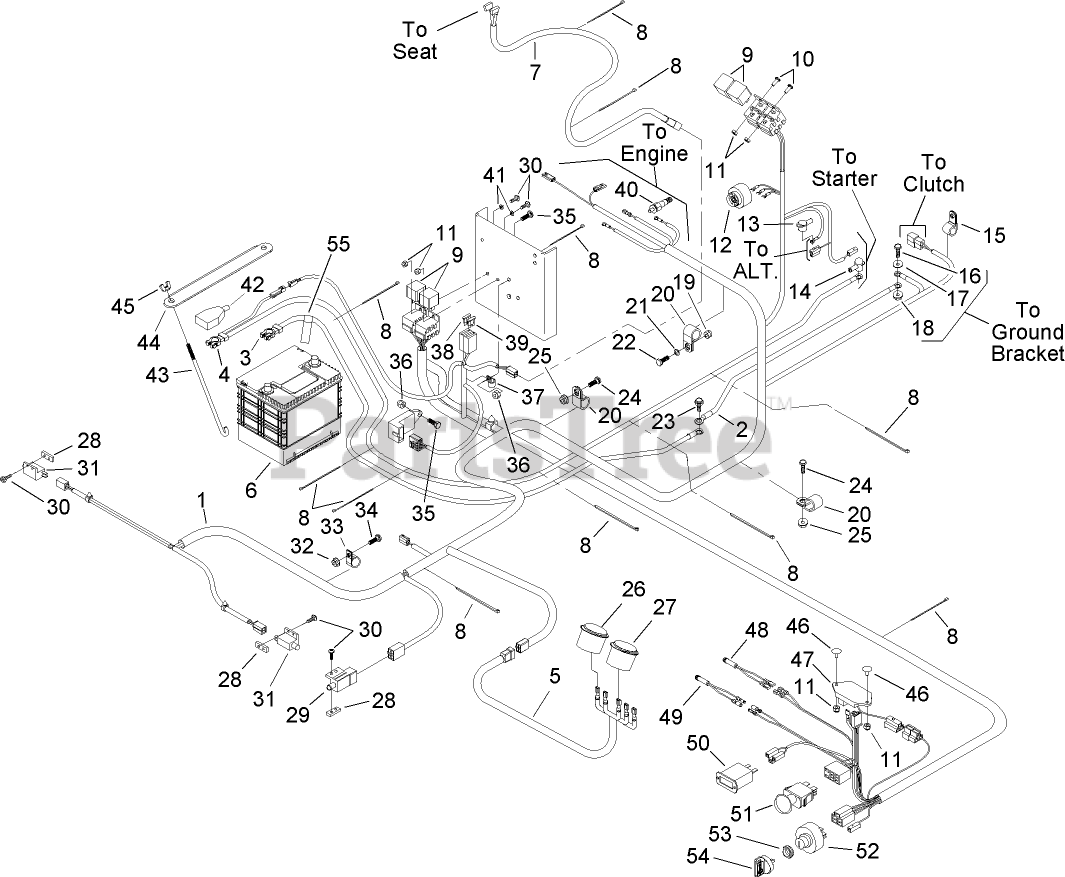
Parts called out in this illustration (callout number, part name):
1	HARNESS-WIRE
2	CABLE-ENGINE NEGATIVE
3	CABLE-BATTERY NEGATIVE
4	CABLE-STARTER
5	HARNESS-GAUGE
6	BATTERY-DRY
7	HARNESS-WIRING, SEAT
8	TIE-PLASTIC
11	NUT-LOCK, NI
12	ALARM-TONE, DUAL
13	CAP-INSULATOR, RED
14	INSULATOR-STARTER
15	CLIP-LOOM
16	SCREW-HH
17	WASHER-FLAT
18	NUT-HHF, WHIZ
19	NUT-LOCK
20	CLIP-LOOM
21	WASHER-FLAT
22	SCREW-HH
23	SCREW-HWHTF
24	SCREW-HH
25	NUT-HF
26	GAUGE-VOLTMETER
27	GAUGE-TEMPERATURE
28	PLATE-TAPPED
29	SWITCH
30	SCREW-PPH
31	SWITCH-OPEN, NORMALLY
32	NUT-HF
33	CLIP-LOOM
34	SCREW-HH
35	SCREW-HH
36	NUT-LOCK, NI
37	CLIP-LOOM
38	FUSE-BLADE TYPE, 20 AMP
39	FUSE-40 AMP
40	SENDER-TEMPERATURE
41	WASHER-FLAT
42	INSULATOR-TERMINAL, BATTERY
43	Bolt-Holddown
44	HOLDDOWN-BATTERY
45	WINGNUT
46	BOLT-CARR
47	MODULE-DELAY, SEAT
48	INDICATOR-LED, RED
49	INDICATOR-LED, AMBER
50	METER-HOUR
51	SWITCH-PTO
52	SWITCH-STARTING, KEY
53	NUT-SWITCH, IGNITION
54	KEY-IGNITION
55	DECAL-INSTRUCTIONS, CHARGING
